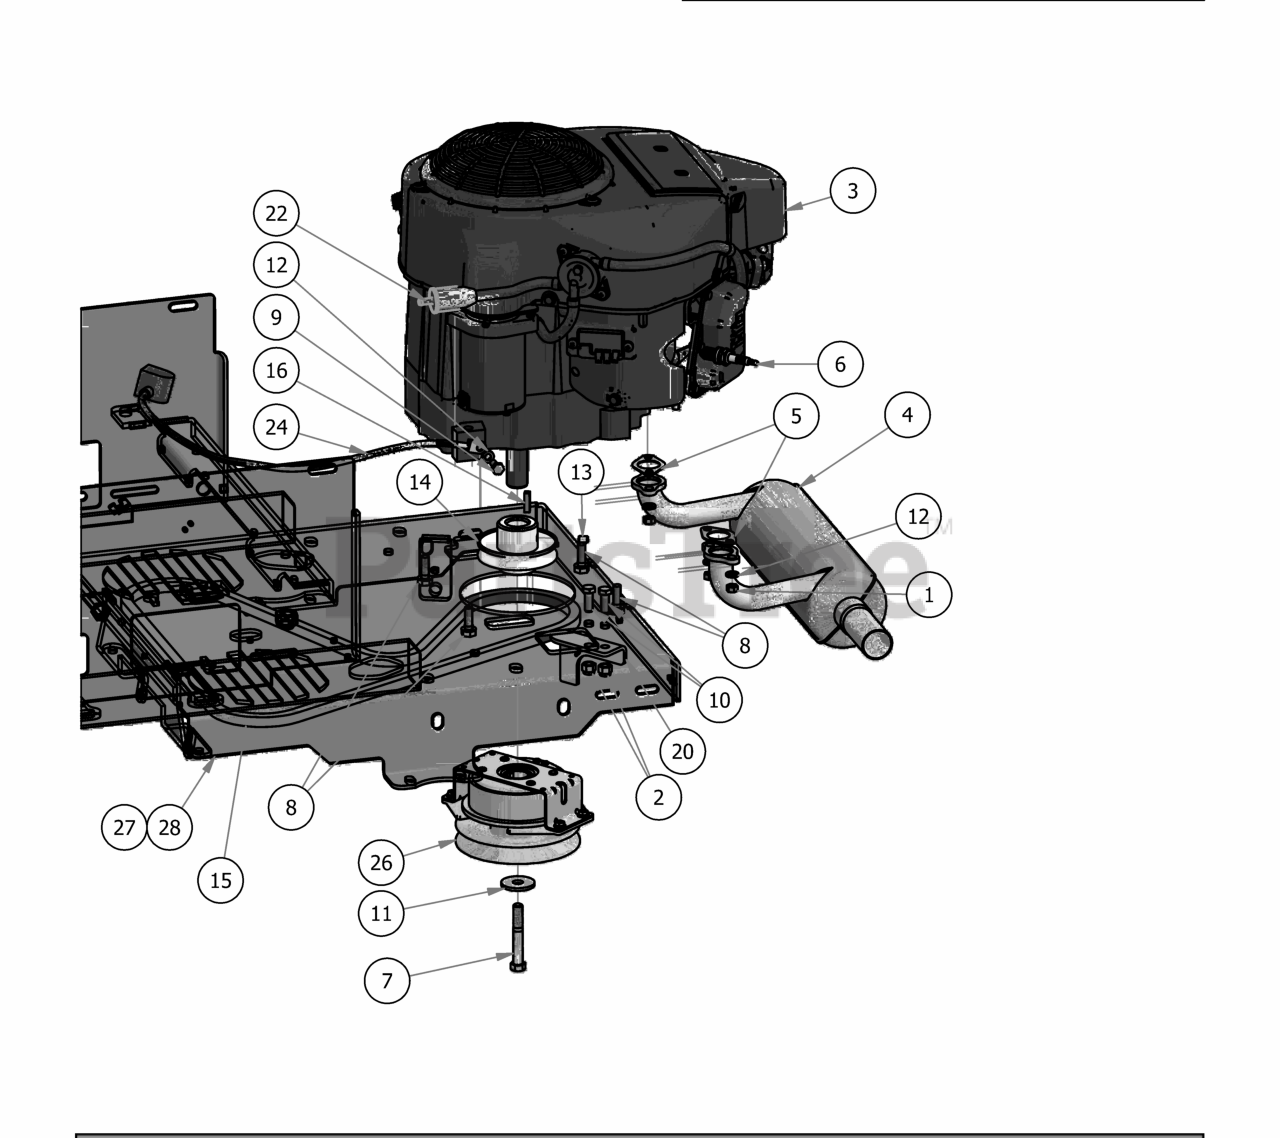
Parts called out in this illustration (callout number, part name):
1	M8-1.25 Zinc Nut
2	3/8 Nylock Nut
3	726cc Kawasaki Engine-FR651V
4	Kawasaki Muffler 1251
5	Exhaust Gasket
6	Spark Plug - Kawasaki
7	7/16"-20 x 3" Hex Bolt Gr. 8
8	3/8 x 1 1/8 bolt
9	M8x1.20x20MM Hex head bolt
10	3/8" x 1" Hex Bolt
11	1/2 Belleville Washer
12	5/16" Lock Washer
13	3/8" Set Screw
14	3-3/4" Motor Pulley
16	1/4" x 1" Key
17	15" Fuel Line Assembly
18	Oil drain Hose
20	2017 MZ Clutch Stop
21	Kawasaki Air Filter
22	Universal Inline Fuel Filter
23	Kawasaki Oil Filter
24	Ground Cable
25	MZ Kohler EPA Canister Assembly
27	2017 MZ/ZT 54"-61" Frame
28	2017 MZ/ZT 42"-48" Frame
29	2017 MZ Magnum Control Panel Assembly
